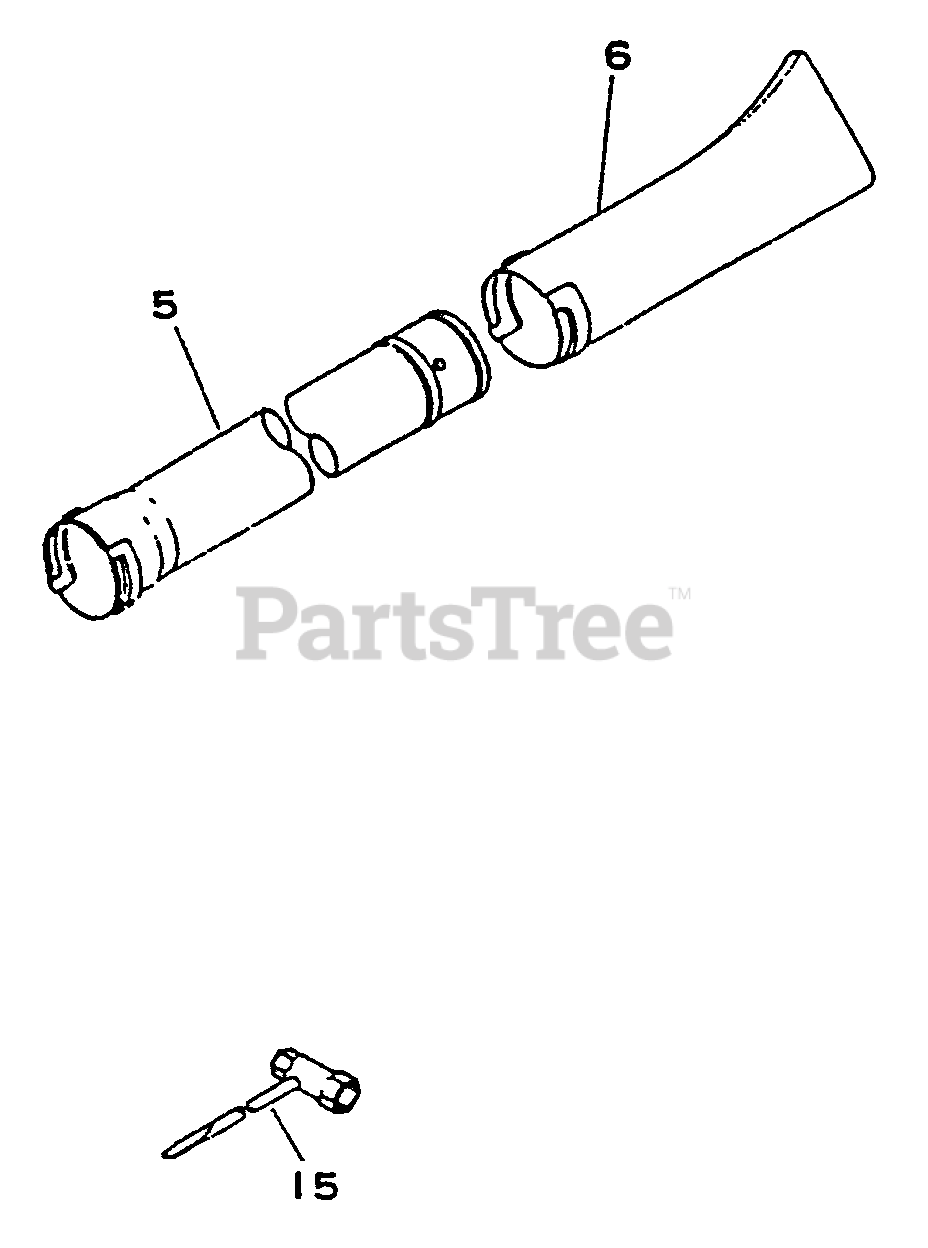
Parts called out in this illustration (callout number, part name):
5	TUBE, BLOWER - STRAIGHT
6	NOZZLE - FAN HEAD
15	WRENCH, W/SCREWDRIVER
